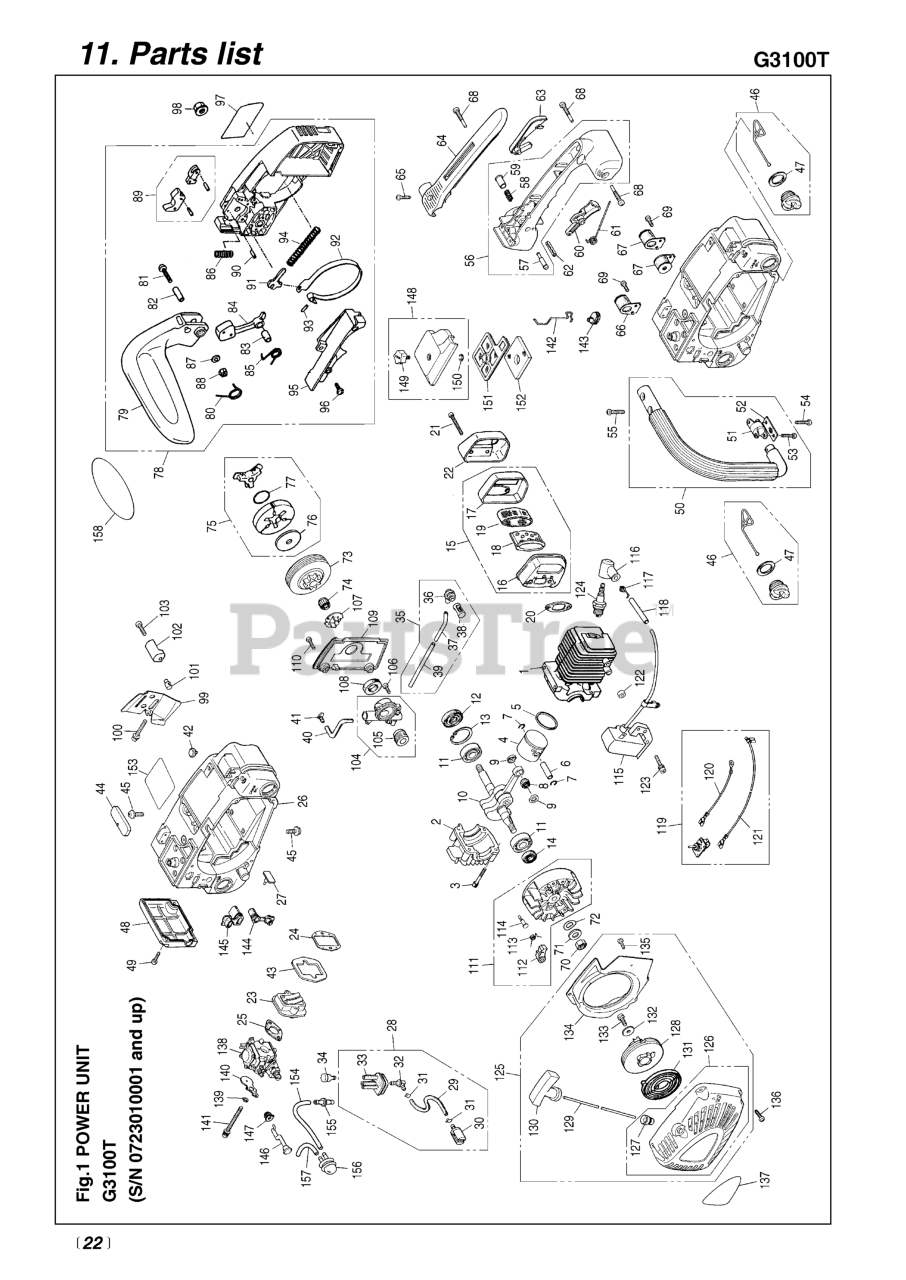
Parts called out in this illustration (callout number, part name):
1	CYLINDER
2	CRANKCASE
3	BOLT, M5 X 30
4	PISTON
5	RING
6	PIN, PISTON
7	RING, SNAP
8	BEARING
9	WASHER (RPLS 3310-41341)
10	CRANKSHAFT
12	SEAL, OIL
13	RING, SNAP, M32 x 1.2
14	SEAL, OIL (RPLS 1100-21210)
15	MUFFLER ASS
17	COVER
18	BAFFLE
19	ARRESTER
23	VALVE ASSEMBLY
25	GASKET
28	FUEL PIPE ASSY
29	PIPE (USE -85411)
30	5500-85400 (RRLS. 1750-85300)
31	CLIP (REPLACES 2841-31280)
34	BREATHER ASSY (RPLS 2630-31270
36	GROMMET (RPLS -31320)
37	JOINT
39	PIPE (USE -85411)
40	PIPE (USE -85411)
41	PIN
42	VALVE A
43	SEAL
45	SCREW
47	GASKET
48	COVER (RPLS -31912)
49	SCREW
50	FRONT HANDLE ASSY (50040056)
51	JOINT (RPLS -32120)
52	STOPPER (RPLS -32150)
57	STOPPER
59	KNOB
60	THROTTLE LEVER
61	SPRING
63	ARM (REPLACES 3356-33352)
65	SCREW
66	JOINT (RPLS -33510)
67	JOINT(C)(SOFT)
69	SCREW
73	DRUM (RPLS 2631-51111)
77	SPRING
81	SCREW
83	SPACER (RPLS -54210)
88	NUT (B)
89	LEVER, BRAKE COMPLETE
91	ARM, SLIDE(RPLS 2670-54410)
92	BAND
93	PIN
94	SPRING, BRAKE (RPLS. 50030121)
95	COVER SPRING
96	SCREW
98	NUT
102	CATCHER, CHAIN (RPLS. -53411)
105	GEAR
107	PLATE
108	SEAL
109	COVER, PUMP (RPLS -55311)
110	SCREW
115	MODULE (RPLS 2631-71111)
116	CAP
117	SPRING
118	TUBE
119	SWITCH SET
120	WIRE, LEAD
123	BOLT
127	GUIDE (RPLS -75120)
135	SCREW
136	SCREW
138	CARBURETOR ASSY
140	PLATE, CHOKE
142	ROD, THROTTLE (RPLS 2630-)
143	GROMMET
144	GROMMET A
145	GROMMET(B)
146	ROD (RPLS -82310)
147	GROMMET
150	RING, SNAP, M4
154	PIPE
155	JOINT (USE 3350-34320)
156	PUMP ASSEMBLY
157	PIPE
